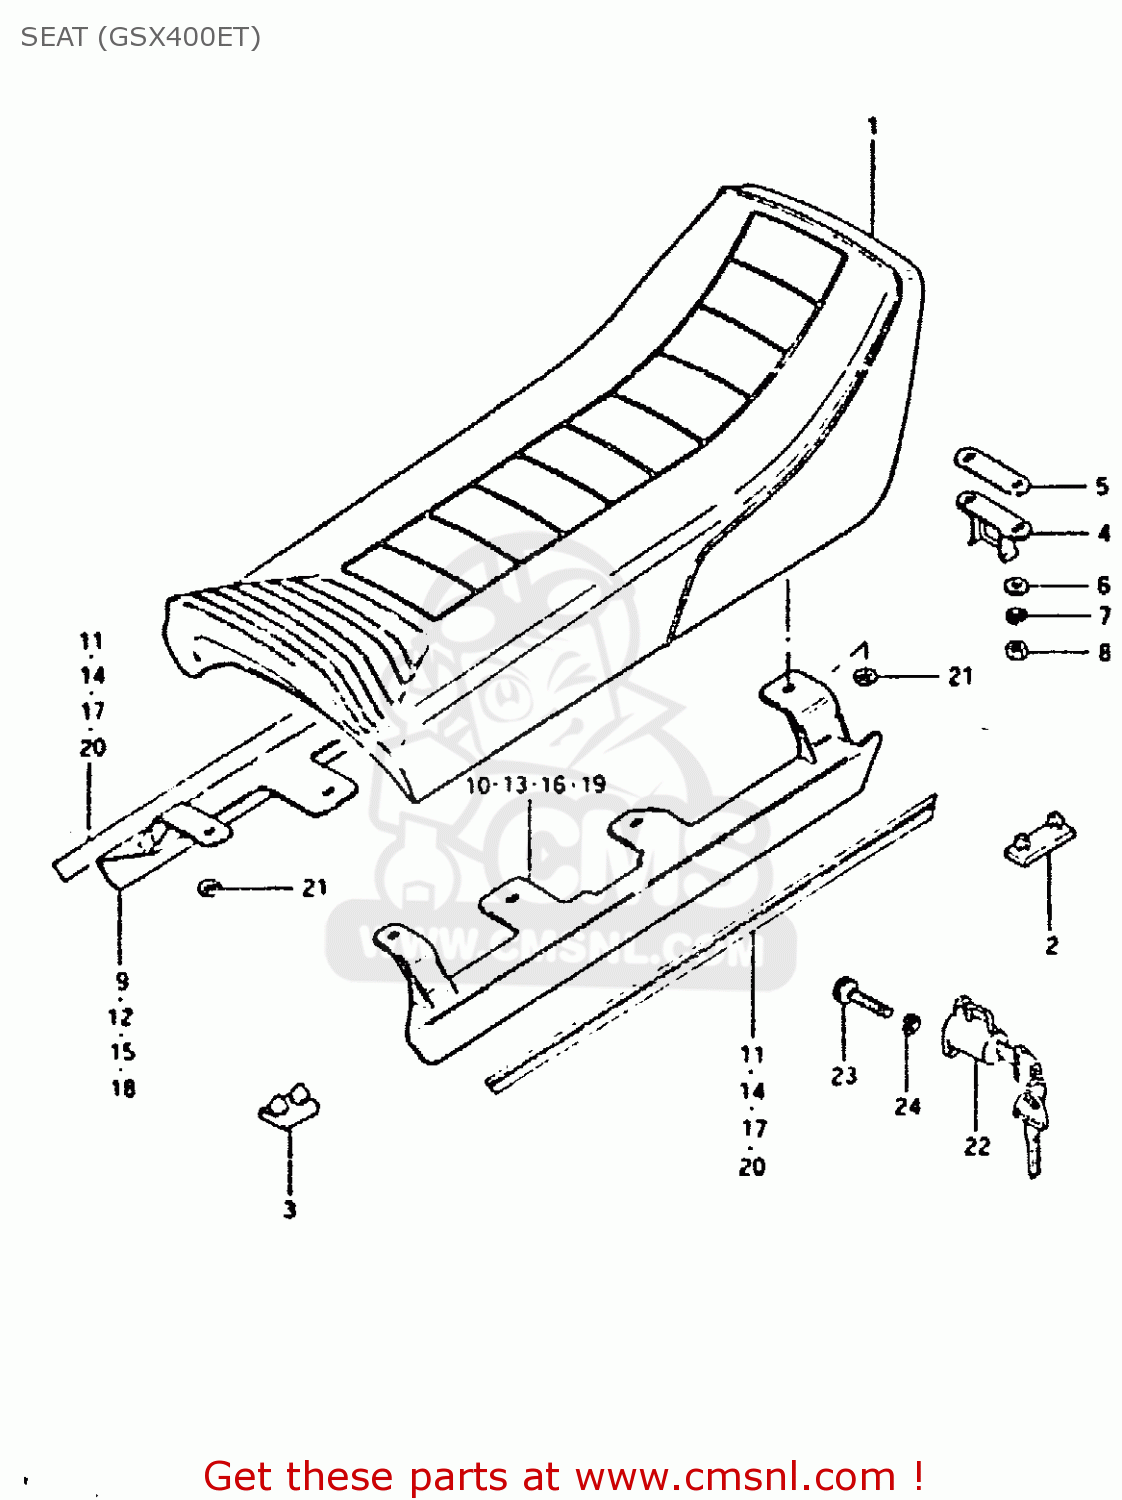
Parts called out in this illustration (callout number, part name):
1	SEAT ASSEMBLY
2	CUSHION
3	CUSHION
4	STRIKER, SEAT LOCK
5	SHIM,SEAT LOCK STRIKER
6	WASHER
7	LOCK WASHER
8	NUT 6MM
9	MOLDING,SEAT
10	MOLDING,SEAT
11	TAPE SET
12	MOULDING, SEAT RH (BLUE)
13	MOULDING, SEAT LH (BLUE)
14	TAPE SET
15	MOLDING,SEAT
16	MOLDING,SEAT
17	TAPE SET
18	MOLDING,SEAT
19	MOLDING,SEAT
20	TAPE SET
21	NUT
22	LOCK ASSEMBLY,HELMET
23	BOLT 6X11
24	LOCK WASHER
